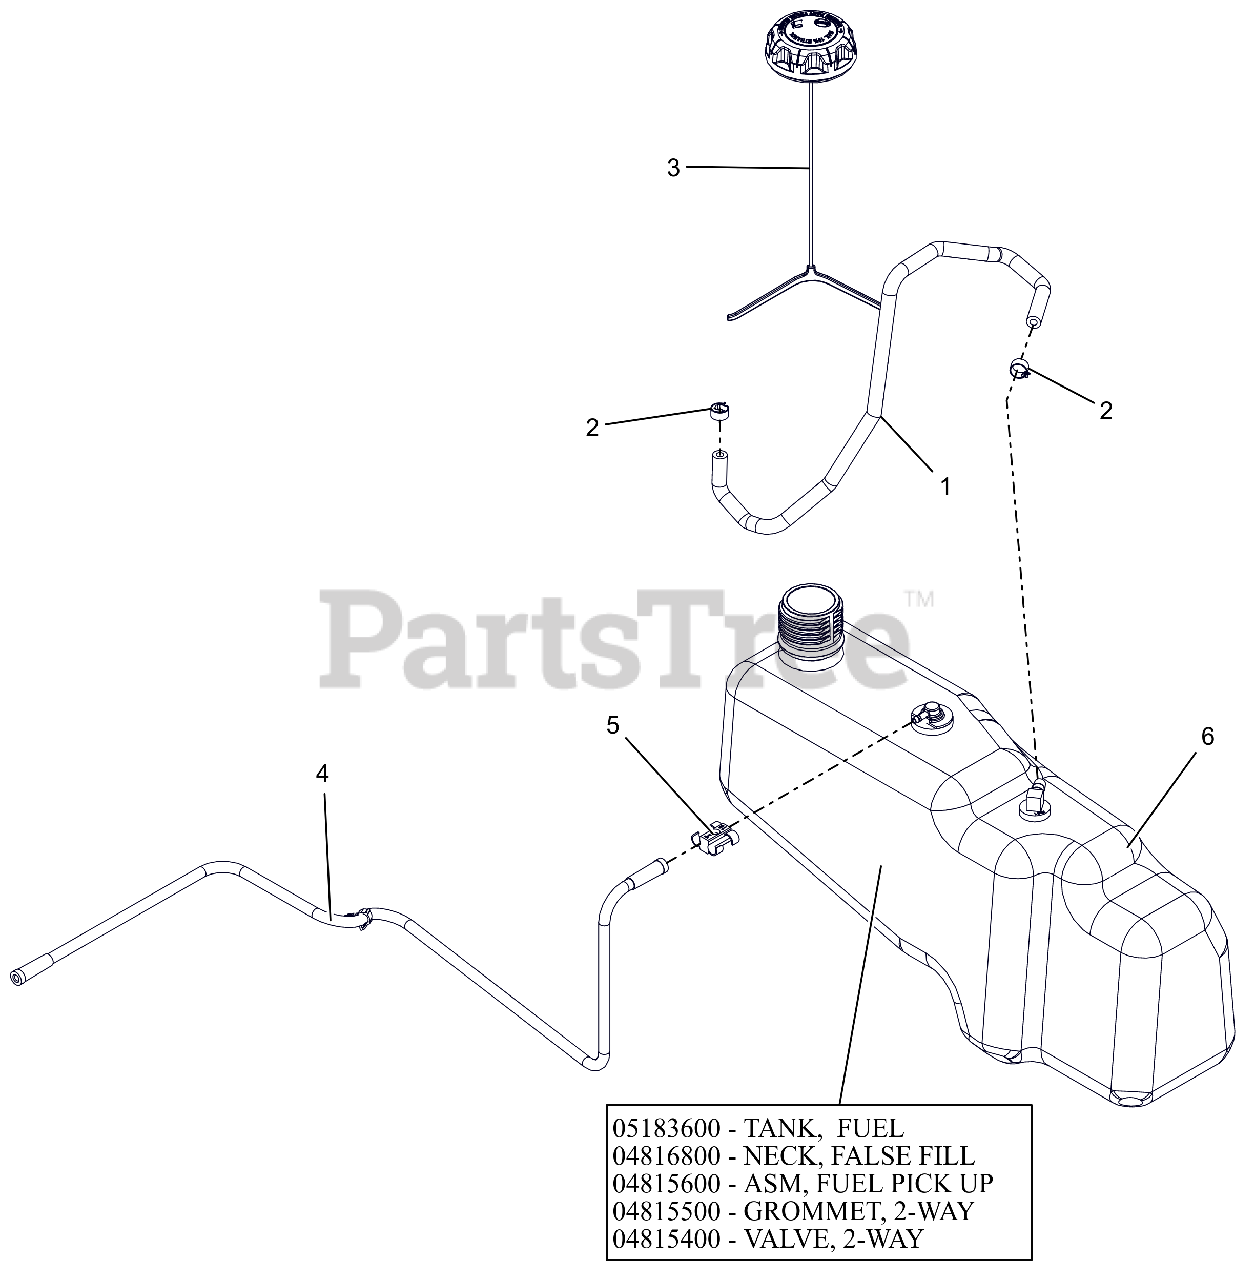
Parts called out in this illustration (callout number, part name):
1	HOSE, .25 LOW-PERM BULK GAS
2	CLAMP, FUEL LINE
3	CAP, FUEL VENT-IN 2.25" RATCH.
4	LINE, FUEL VENT KAWI
5	CLIP, T, .38-.50
6	ASM, FUEL TANK - ZTX
6	TANK, FUEL-ZTX
6	NECK, FALSE FILL ZOOM/ZT
6	ASM, FUEL PICK-UP ZOOM/ZT 2015
6	GROMMET, 2-WAY
6	VALVE, 2-WAY
